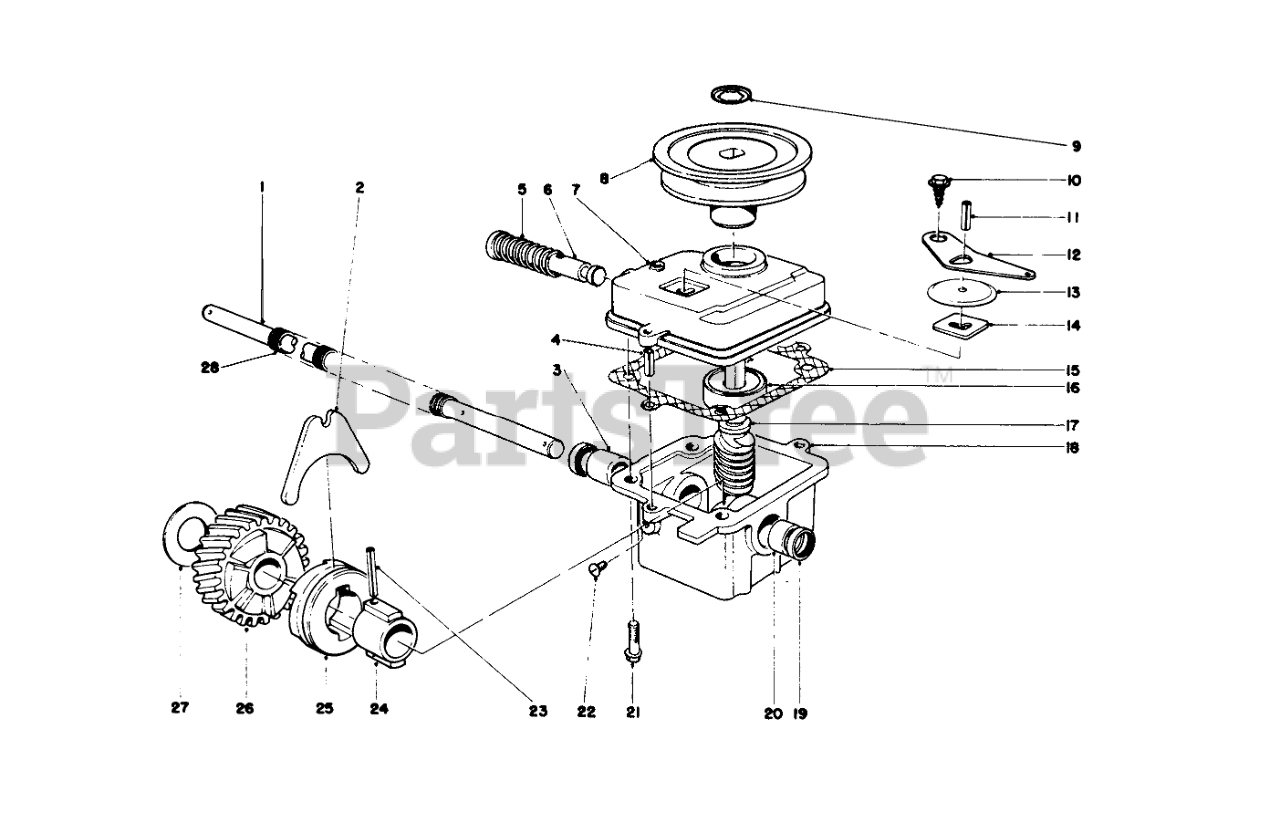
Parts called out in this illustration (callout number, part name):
1	Drive Shaft
2	SHIFTER FORK
3	Bushing
4	3/16 X 1/2 ROLL PIN
5	SPRING
6	Shift Rod
7	Cover Gear Case
8	PULLEY
9	PUSH-ON 93-3236
10	Self Tapping Screw
11	PIN-ROLL
12	SHIFTER ARM
13	TRANS DUST COVER
14	LATCH PLATE
15	GASKET
16	Bearing
17	Worm Shaft (Incl. Ref. #26)
18	Gear Case (Incl. Ref. #3, 19-20)
19	Seal
20	Bushing
21	Screw
22	NYLON SCREW
23	COIL PIN
24	SLEEVE
25	CLUTCH JAW
26	Helical Gear
27	THRUST WASHER
28	DRIVE SHAFT COVER
